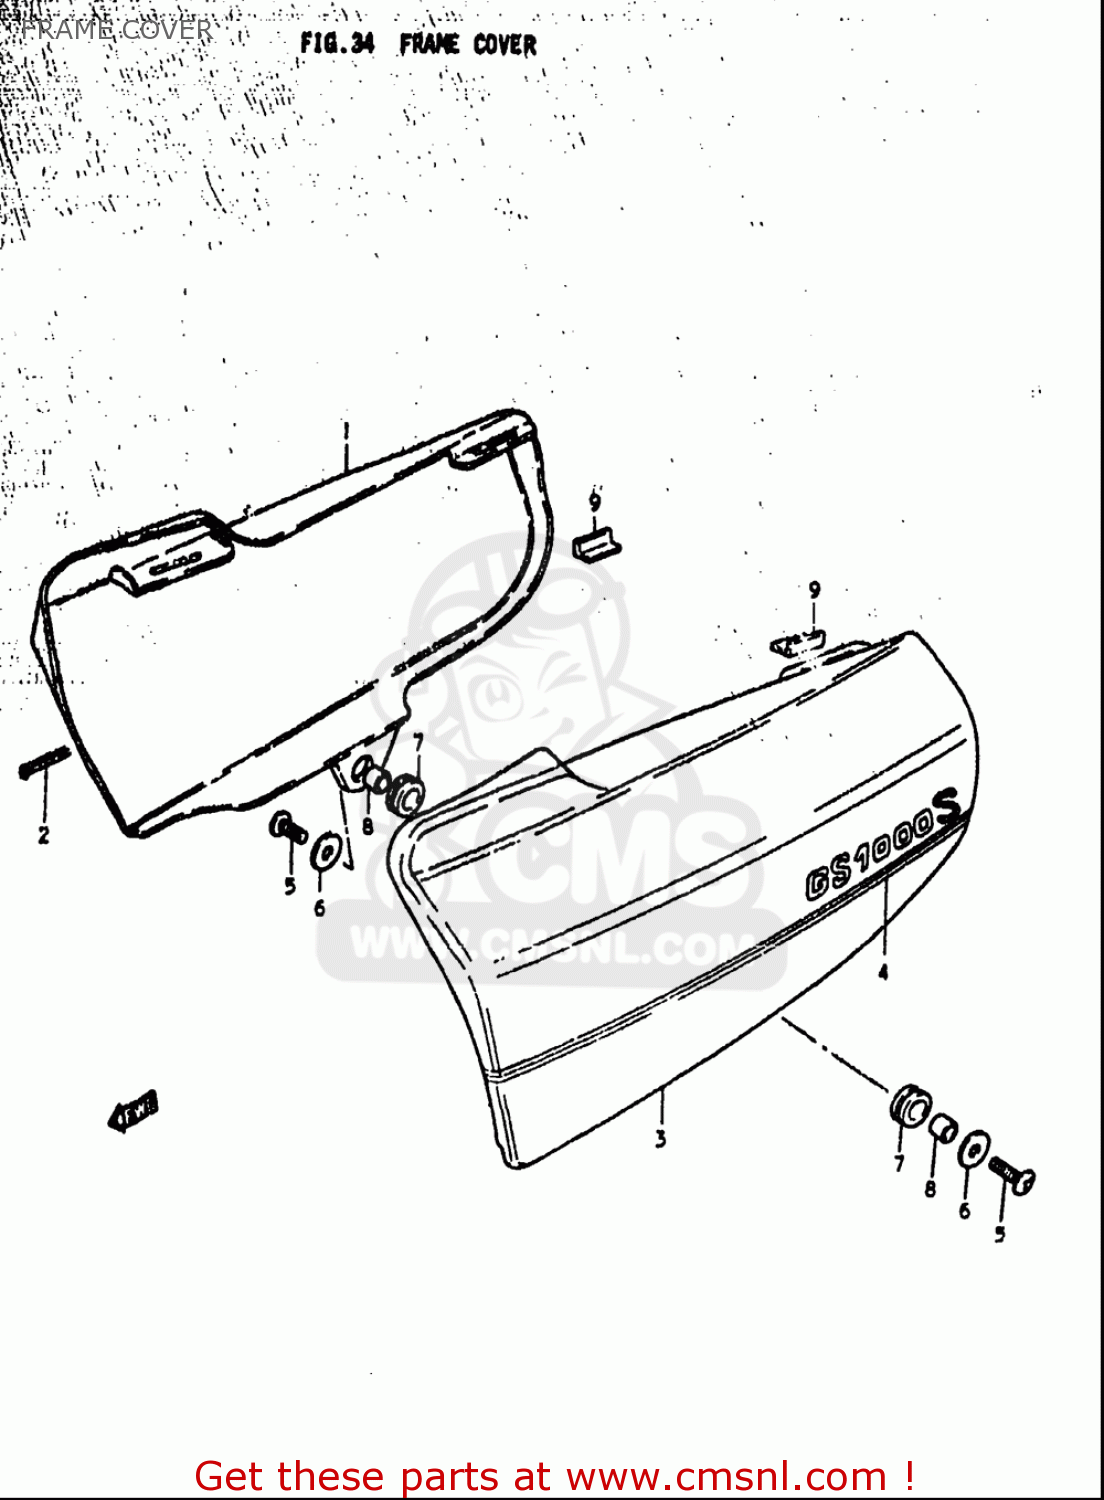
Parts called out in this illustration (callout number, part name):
1	COVER,FRAME,R
3	COVER,FRAME,L
5	SCREW
6	WASHER(6.5X18X1.6)
7	CUSHION
8	SPACER(6.5X10X10)
9	CUSHION,FRAME COVER
